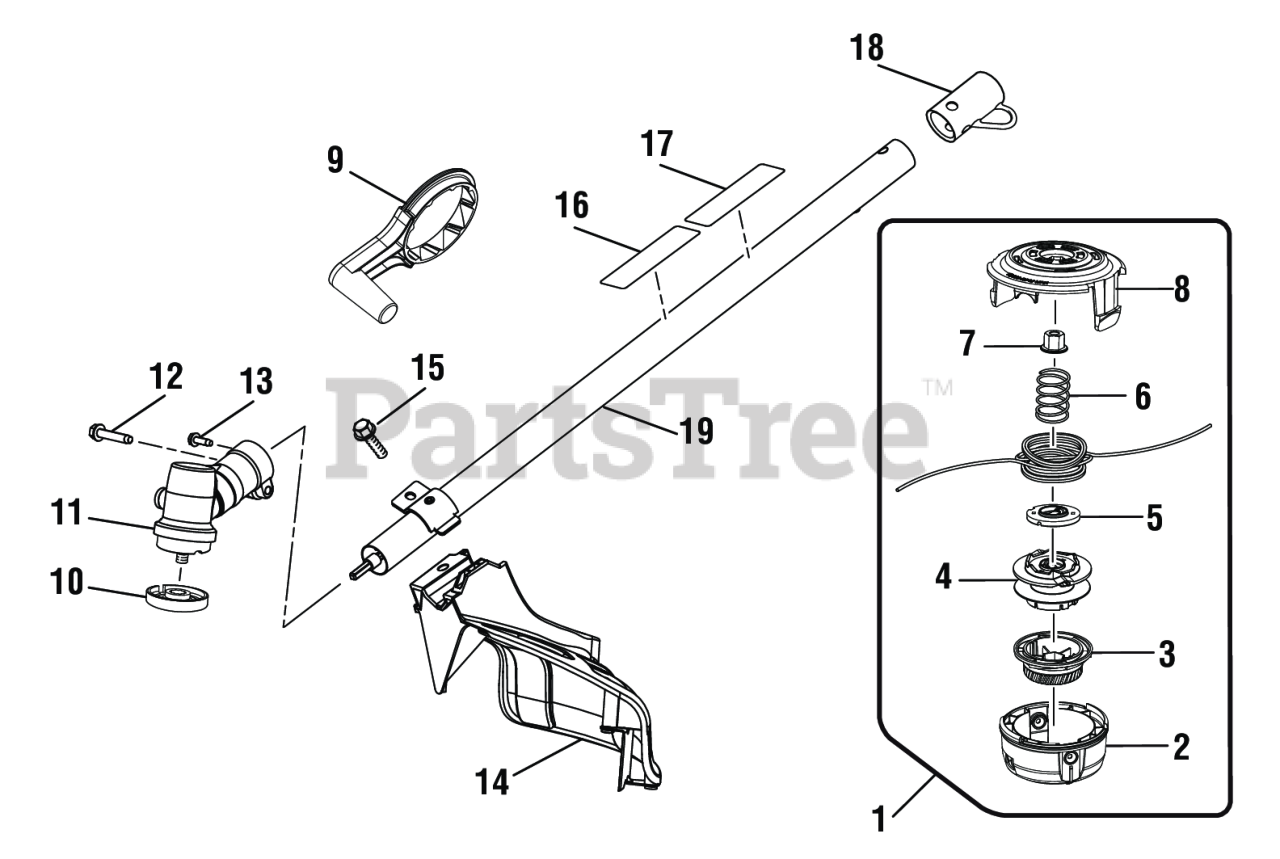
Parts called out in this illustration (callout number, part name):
1	Trimmer Head Assembly (.095)
2	Lower Housing
3	Bump Knob (Green)
4	Spool Assembly
5	String Guide
6	Compression Spring
7	Hex Nut (M8, Left Hand Threads)
8	Upper Housing
9	Crank Handle Assembly
10	FLANGED WASHER
11	Gear Case Assembly
12	Screw (1/4-20 x 1-1/4 in., Hex Washer Hd. S.T.)
13	Screw w/Washer (10-24 x 5/8 in., Hex Hd. T.F.)
14	Grass Deflector Assembly
15	SCREW (#1/4-20 X 1-1/4 in. HEX WASHER HD.)
16	Ryobi EXPAND-IT Label
17	Warning Icon Label
18	Storage Hanger Cap
19	Straight Shaft Assembly
